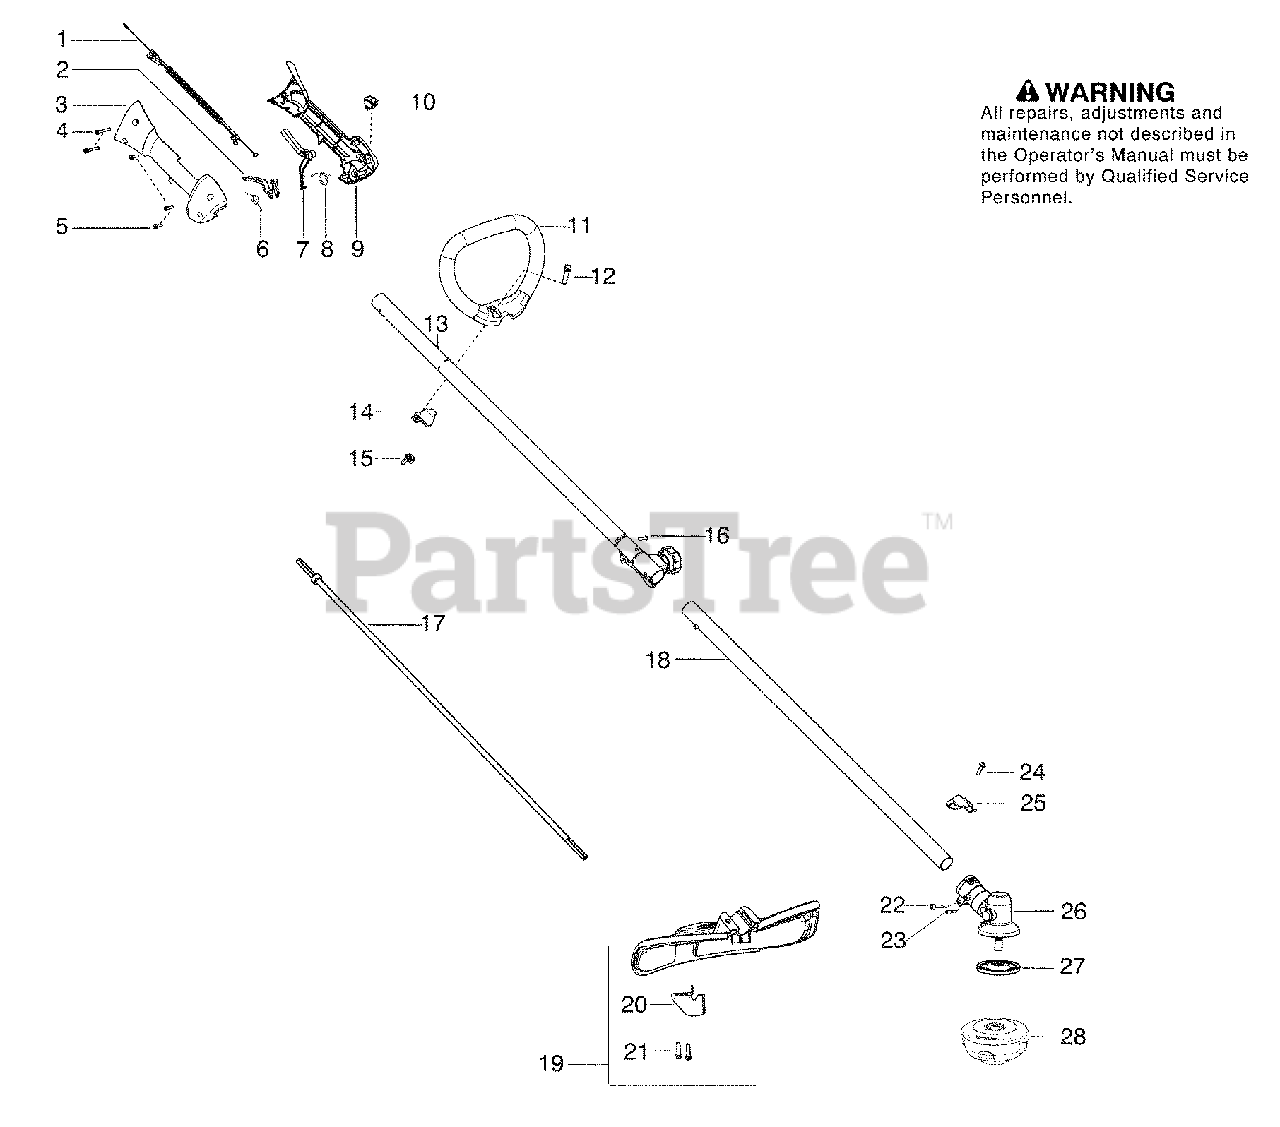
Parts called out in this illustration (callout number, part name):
1	Assy-Cable/Wire Harness
3	Housing-Throttle (RH)
6	Spring-Trigger
7	Lockout-Throttle
8	Spring-Lockout
9	Housing-Throttle (LH)
10	Kit-Switch
11	Handle - Assist
13	Kit-Driveshaft Upper
14	Clamp - Handle Assist
15	Wingnut
18	Kit-Lower Shaft
19	Kit-Shield
20	Limiter - Line
25	Bracket-Shield
26	Assy-Gearbox
27	Driver Disc
28	Assy-T25 Cutting Head
